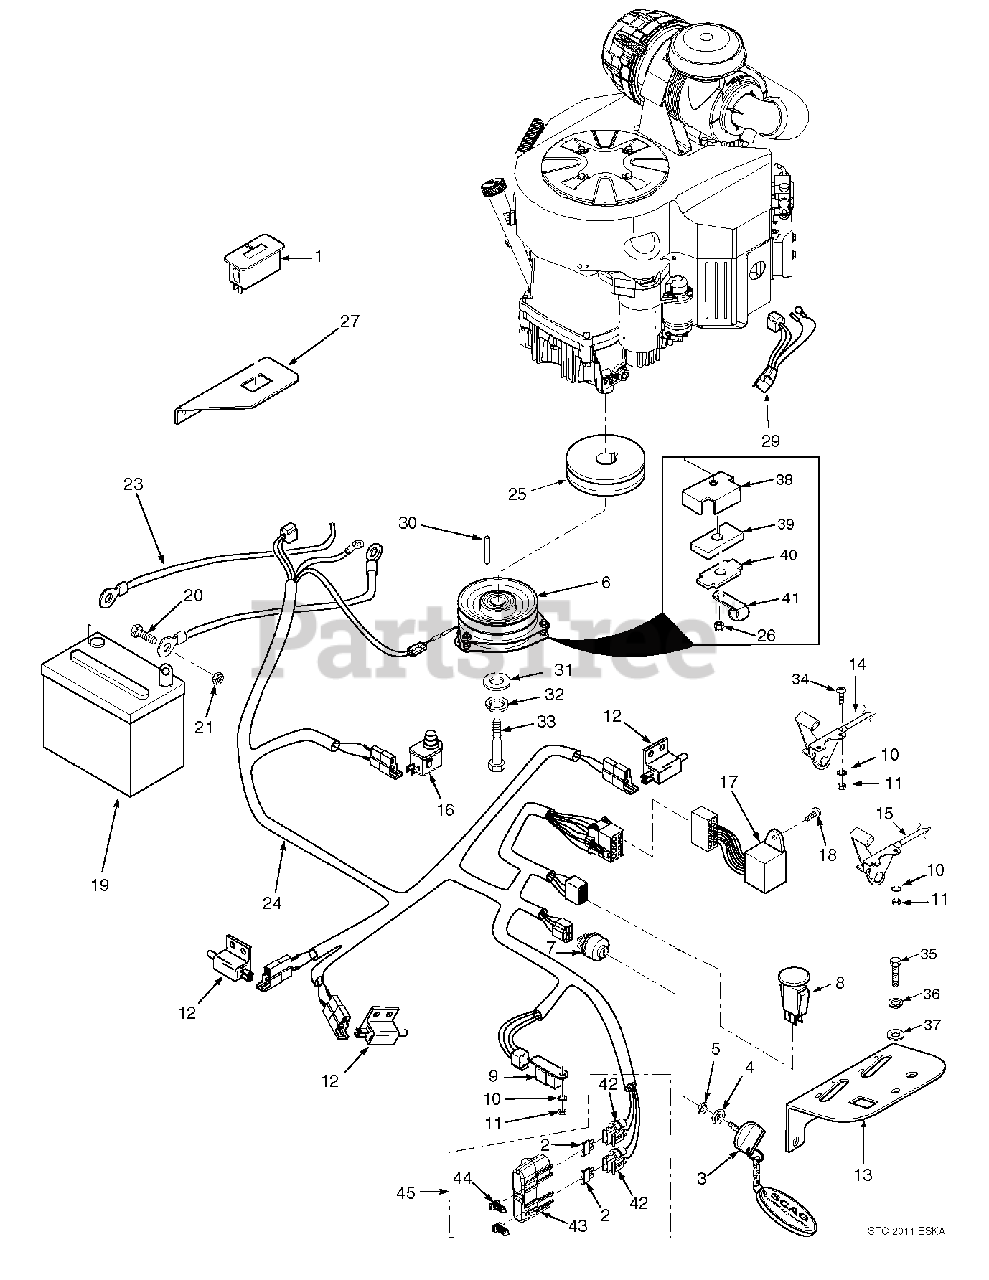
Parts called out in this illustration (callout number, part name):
1	Hourmeter
2	Fuse, 20 amp
3	Key, Ignition
4	Nut, Hex 5/8-32
5	Lockwasher, 5/8" Internal
6	Electric PTO Clutch GT3.5
7	Switch, Ignition
8	Switch, PTO
9	Relay
10	Lockwasher, #10 External Tooth
11	Nut, Hex #10-32
12	Switch, N/O
13	Panel, Instrument
14	Choke & Throttle Control
14	Choke Control
15	Throttle Control
16	Switch, Seat
17	Module, Interlock
18	Screw, #10-32 x .5" Phillips Head
19	Battery, 350CCA
20	Bolt, Hex Head 1/4-20 x .5"
21	Nut, Hex 1/4-20
22	Cable, Battery Black
23	Cable, Battery Red
24	Wiring Harness, Main
24	Wire Harness, Main
25	Pulley, 5.45 OD x 1.125" Bore
26	Nut, Elastic Stop 5/16-18 Key
27	Mounting Bracket, Hour Meter
28	Screw, #10-32 x 1.5" Phillips Head
29	Adapter, Wiring Harness
30	Key, 1/4 x 1/4 x 3-1/4"
31	Flatwasher, 7/16-.469 x 1-3/4" x 1/4"
32	Lockwasher, 7/16"
33	Bolt, Hex Head 7/16-20 x 2-1/2" UNF
34	Screw, #10-32 x 3/4"
35	Bolt, Hex Head 5/16-18 x 3/4"
36	Lockwasher, 5/16"
37	Flatwasher, 5/16-.375 x .875 x .083
38	Backing Plate
39	Rubber Pad, Clutch Stop
40	Plate, Backing
42	Fuse Holder
43	Cover, Sealed Double
44	Clip, Wire
45	Double Fuse Assembly, Sealed
